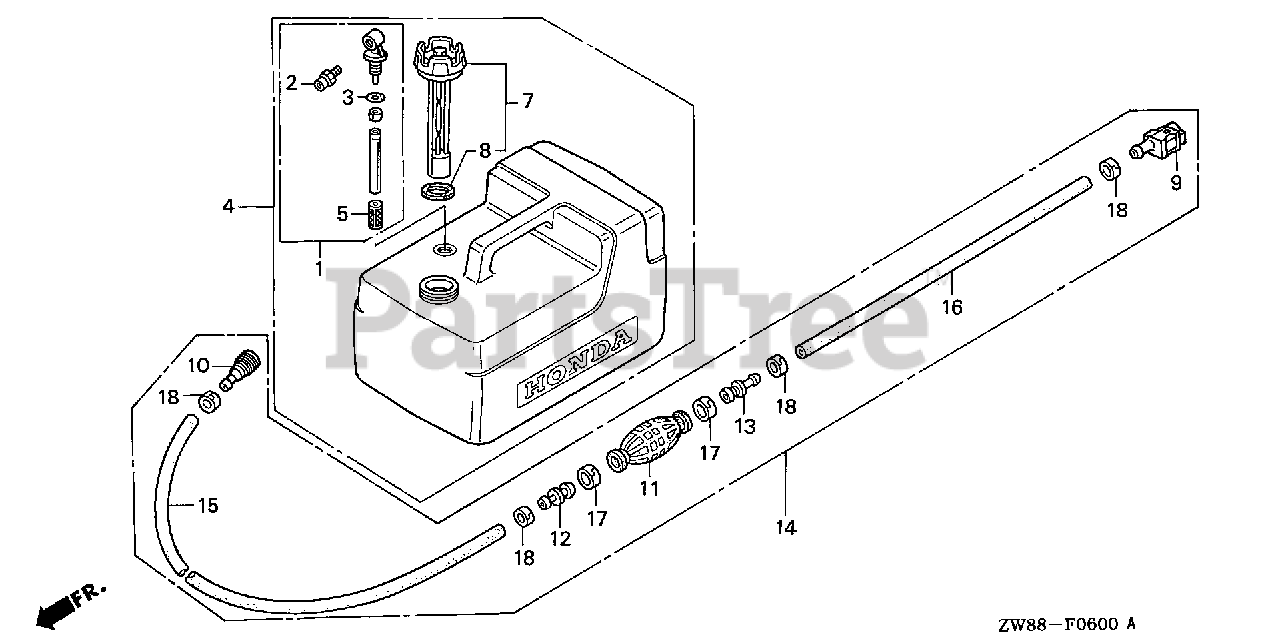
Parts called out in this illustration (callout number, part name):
1	JOINT ASSY., FUEL
2	FITTING, QUICK DISCONNECT
3	O-RING
4	TANK ASSY., FUEL
5	FILTER, FUEL
7	CAP, FUEL FILLER
8	GASKET, FUEL CAP
9	CONNECTOR ASSY., FUEL (A)
10	CONNECTOR, FUEL
11	BULB, PRIMER
12	VALVE, IN.
13	VALVE, OUTLET
14	TUBE ASSY., FUEL
15	TUBE, FUEL LONG (7.3X2000)
16	TUBE, FUEL SHORT (6.3X500)
17	BAND, TUBE CLIP (20MM)
18	BAND, TUBE CLIP (12.5MM)
